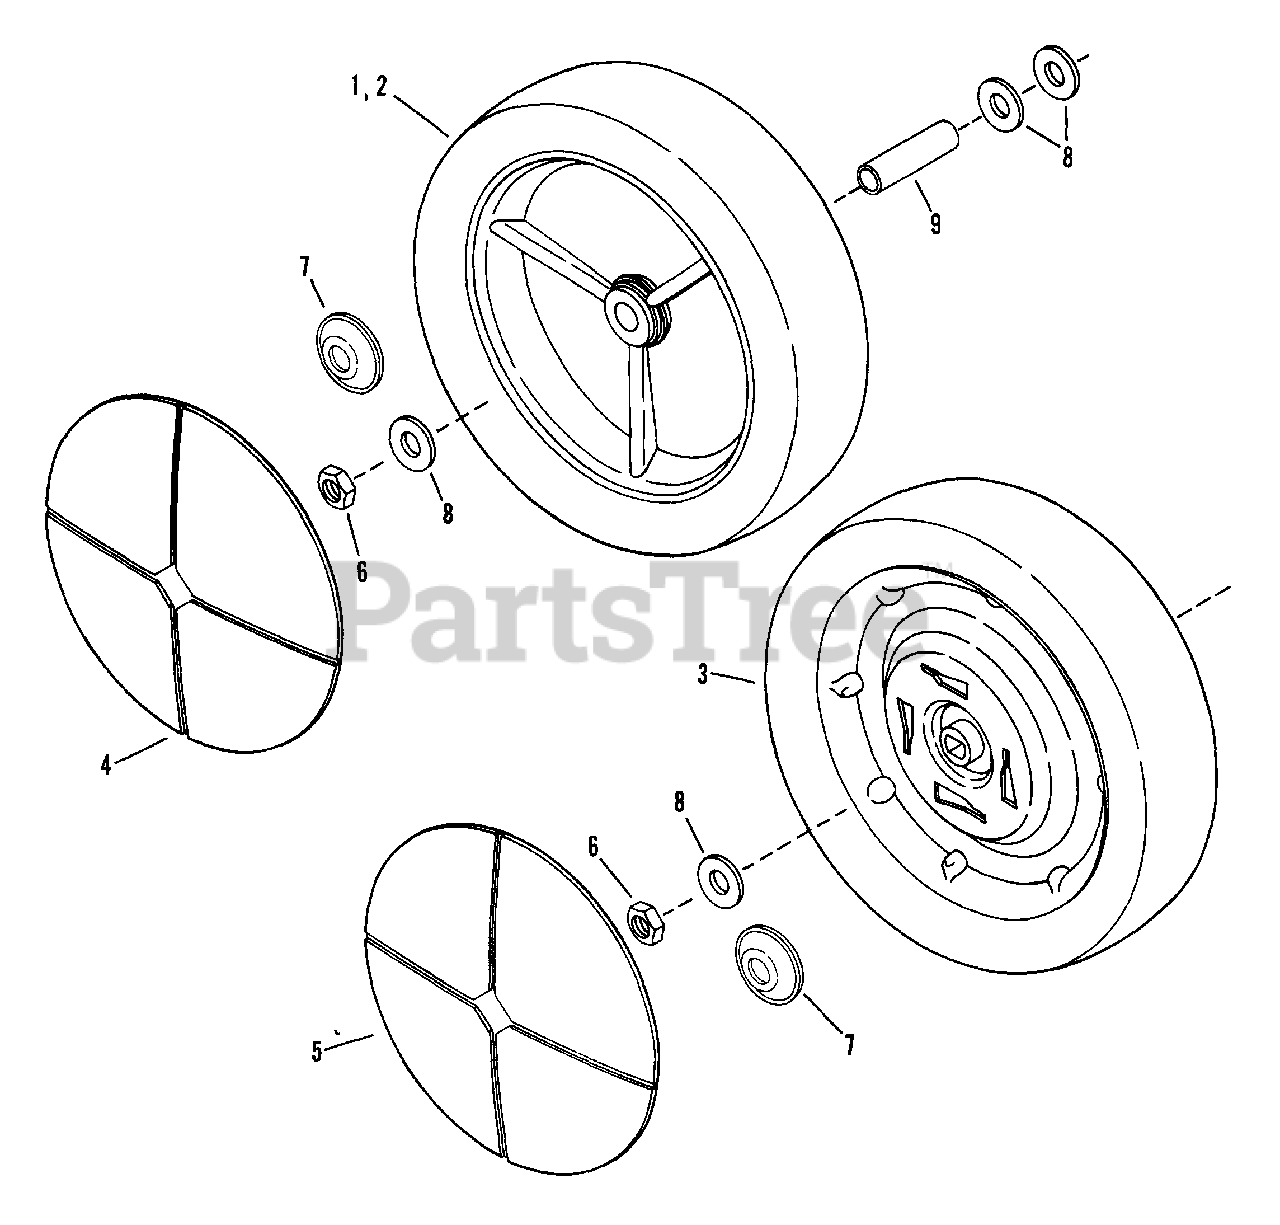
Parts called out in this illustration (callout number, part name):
1	WHEEL, 9 x 2.00 Plastic Rim
2	WHEEL, 9 x 2.00 Plastic Rim
3	WHEEL, 9 x 2.00 Steel Rim
4	COVER, Wheel
5	COVER, Wheel
6	NUT, 5/16-18 Hex Center Lock
7	CAP, Deep-Dish Hub
8	WASHER, 7/16 Flat
9	BUSHING, Axle (Push)
